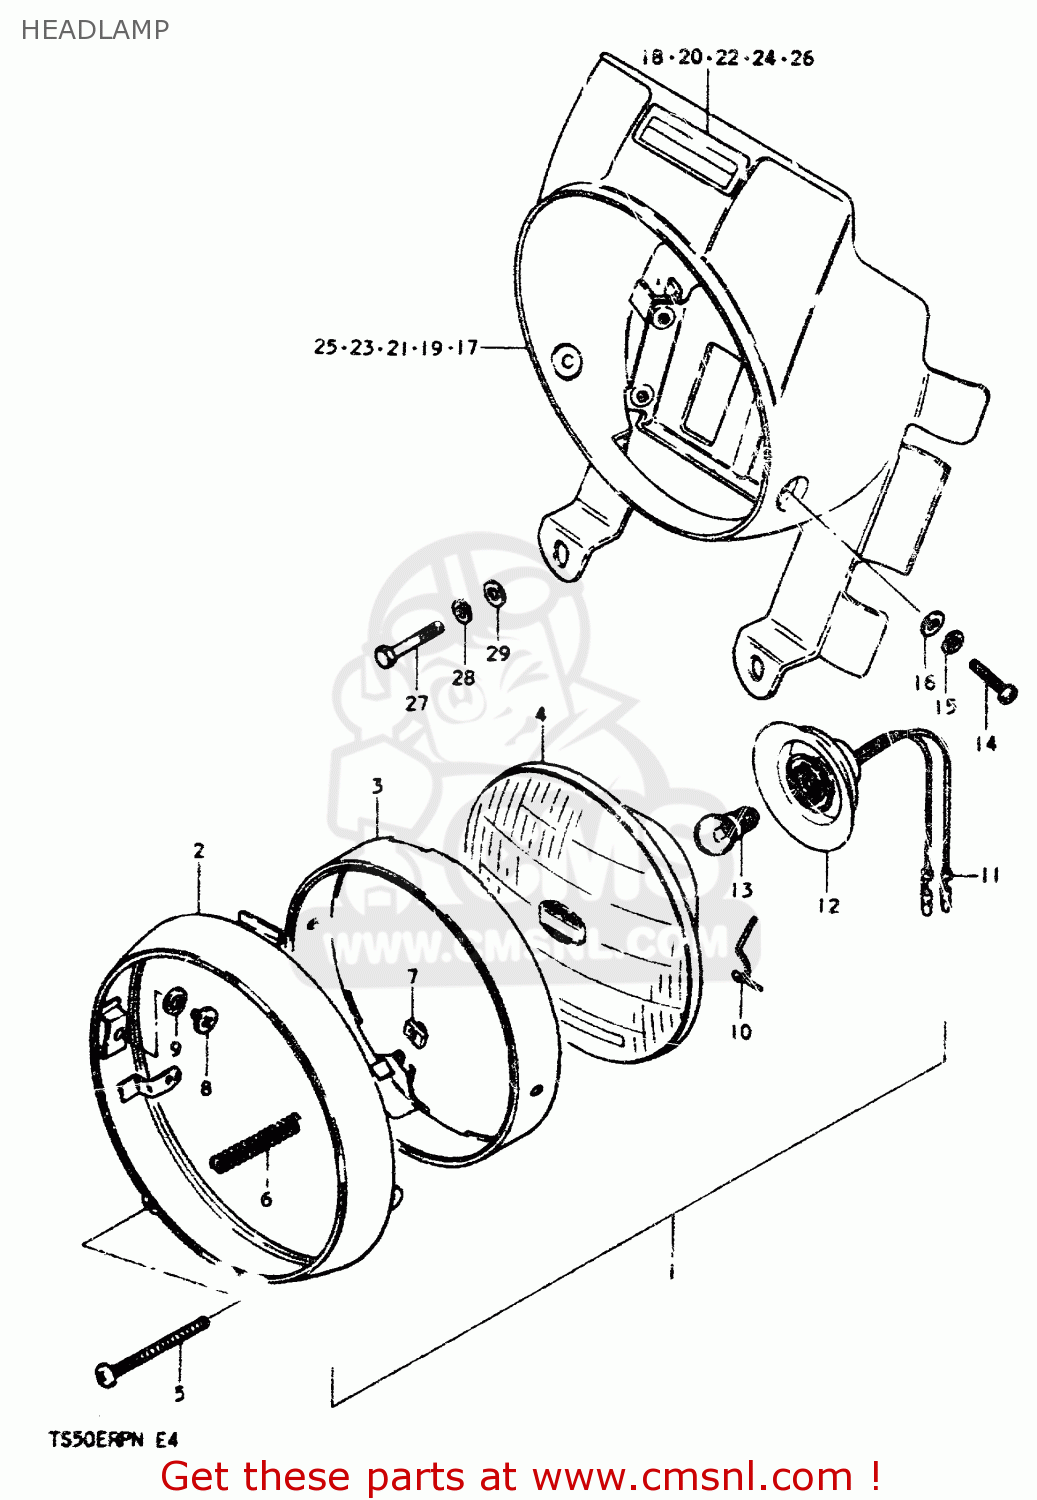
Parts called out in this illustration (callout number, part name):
1	HEADLAMP ASSY
2	RIM
3	RETAINER
4	UNIT
5	SCREW,HEADLAMP ADJUST
6	SPRING,ADJUSTING
7	NUT
8	SCREW
9	LOCK WASHER
10	SPRING
11	SOCKET
12	COVER
13	BOLT (6V,6W)
14	SCREW
15	LOCK WASHER
16	WASHER
17	HOUSING, HEADLAMP
18	TAPE, HOUSING
19	HOUSING HEADLAMP
20	TAPE, HOUSING
21	HOUSING, HEADLAMP
22	TAPE, HOUSING
23	HOUSING, HEADLAMP
24	TAPE, HOUSING
25	HOUSING, HEADLAMP
26	TAPE, HOUSING
27	BOLT
28	LOCK WASHER
29	WASHER
